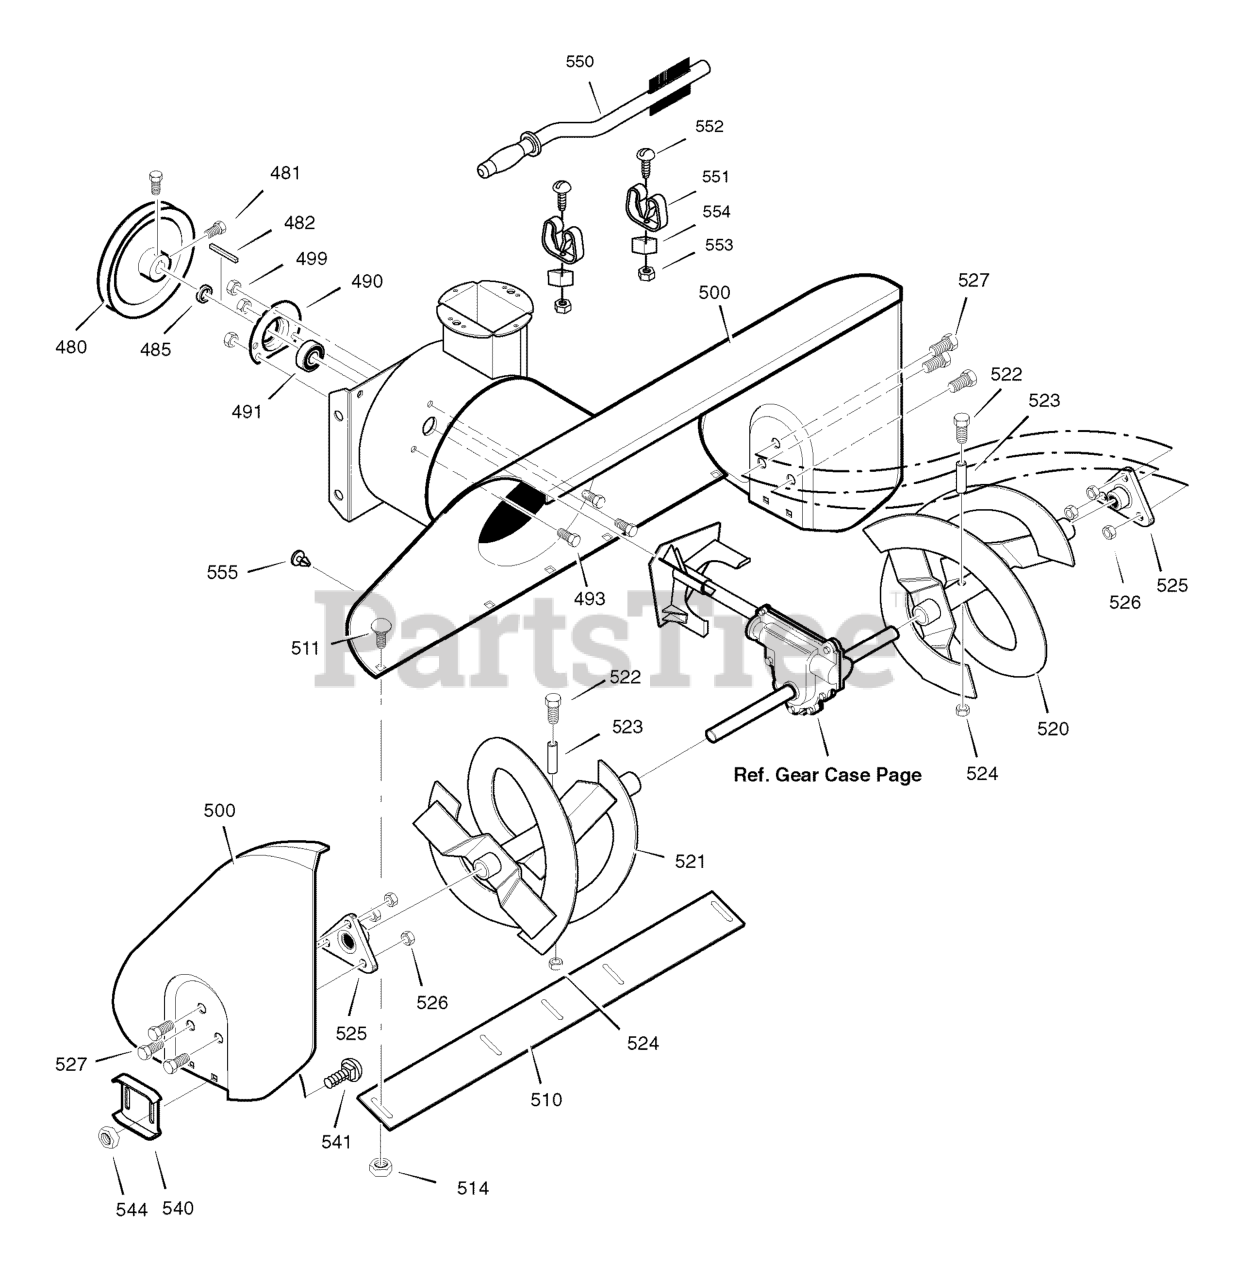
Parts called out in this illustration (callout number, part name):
480	PULLEY, 8.40 V4L .67id
481	SCREW, 5/16-18 x 0.63
482	KEY, SQUARE 3/16 X 3/4
485	SPACER, FRICTION PULLEY
490	RETAINER, BALL BEARING
491	BEARING, BALL
493	BOLT, HEX 5/16-18 X 0.62
499	NUT, 5/16-18 HEXWDFLLK
500	HOUSING, ASSEMBLY
510	BLADE, SCRAPER
511	BOLT, 5/16-18 X 34
514	NUT, 5/16-18 X 0.62
520	AUGER ASSEMBLY, LH
521	AUGER ASSEMBLY, RH
522	SCREW, 1/4-20 X 1.75
523	SPACER, SLEEVE
524	NUT, 1/4-20
525	BEARING, FLANGE
526	NUT, 5/16-18
527	SCREW, 5/16-18 x 0.75
540	SKID, HEIGHT ADJUST
541	BOLT, 5/16-18 X 0.5
544	NUT, 5/16-18
550	BRUSH, CLEANOUT
551	CLIP, RETAINER
552	SCREW
553	NUT
